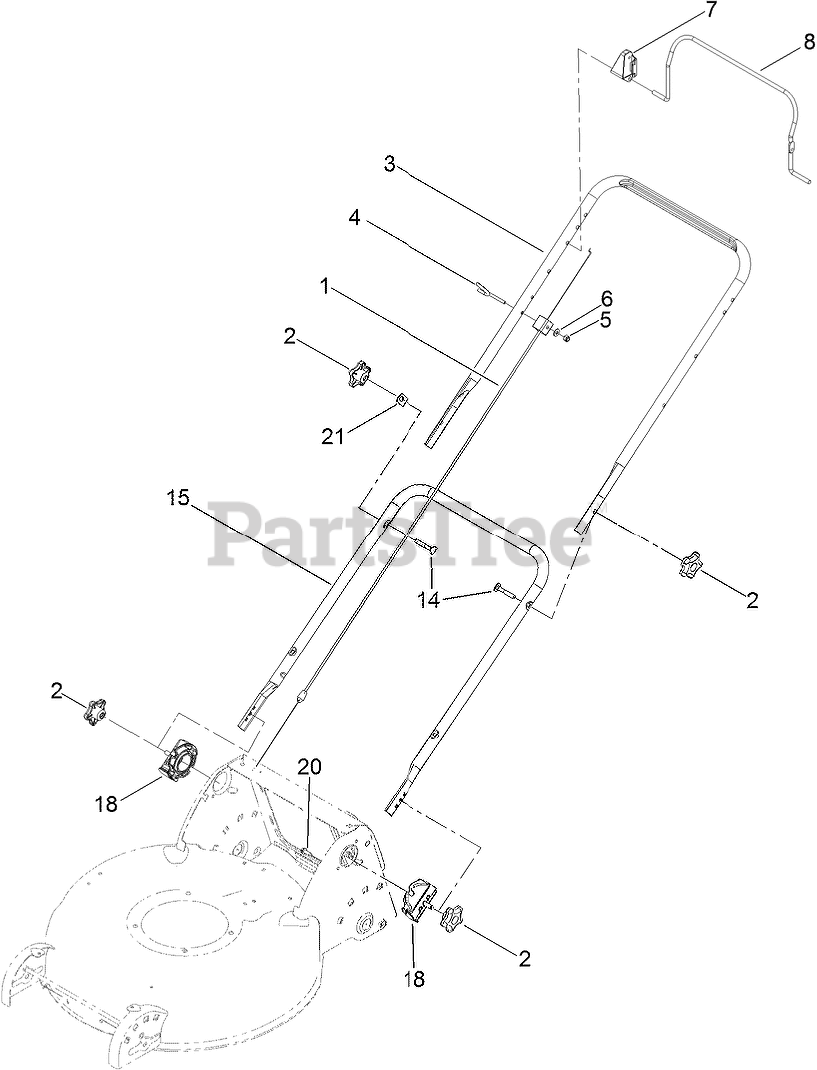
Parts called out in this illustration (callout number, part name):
1	Cable-Brake
2	KNOB-HANDLE
3	Handle-Upper
4	GUIDE-ROPE
5	WASHER-FLAT
6	NUT-LOCK, NI
7	STOP-PIVOT
8	Bail-Brake
14	SCREW-HANDLE
15	HANDLE-LOWER
18	HANDLE MOUNT ASM
20	SCREW-HWHTF
21	CLAMP-R
